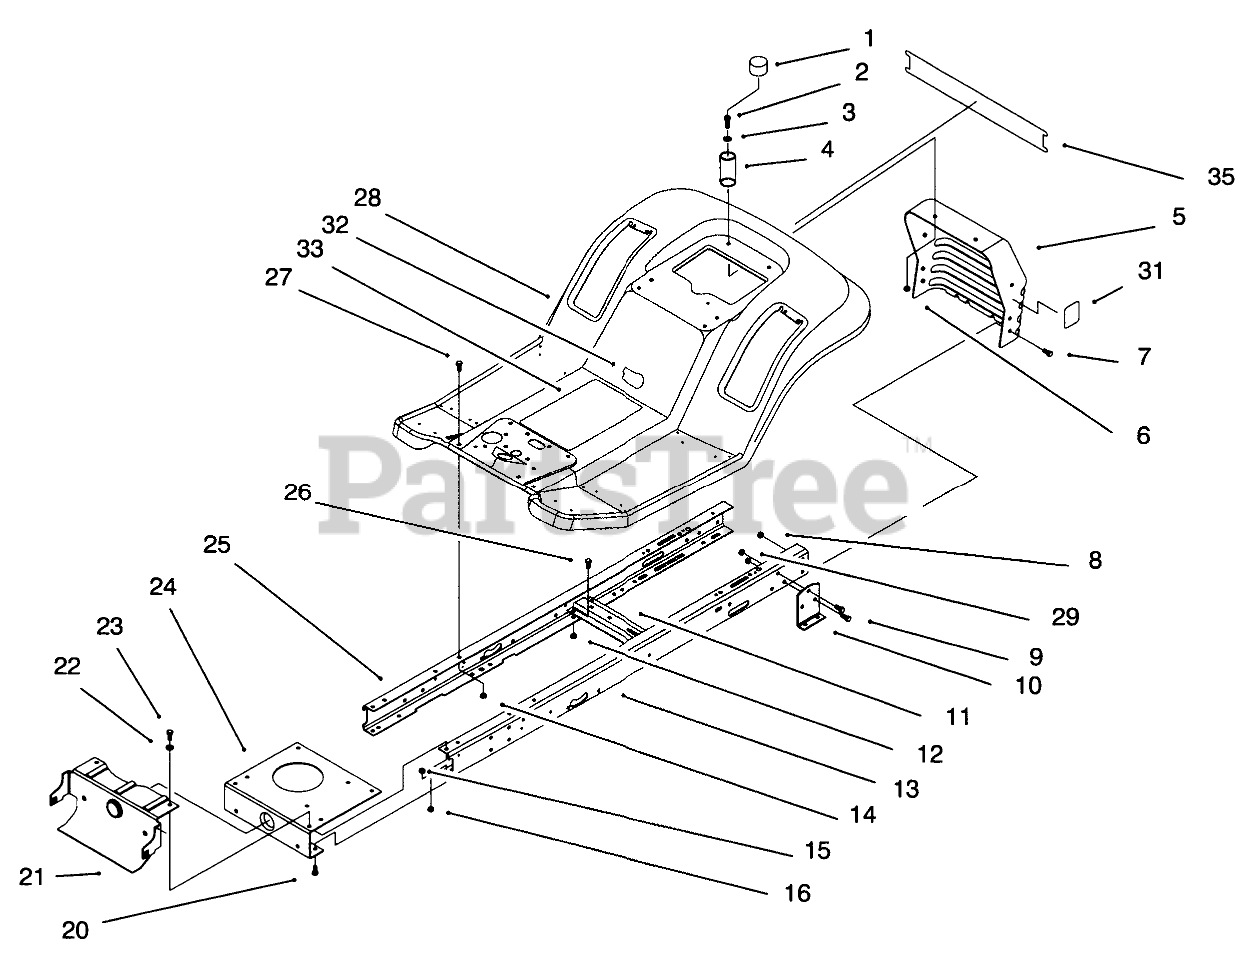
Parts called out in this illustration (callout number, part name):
1	CAP-PROTECTOR
2	SCREW-HH
3	WASHER-PLAIN
4	SPRING-COMPRESSION
5	Panel-Rear
6	NUT-LOCK, NI
7	SCREW-HH
8	NUT-LOCK, NI
9	SCREW-HH
10	BRACKET-TRANSAXLE, MOUNTING
11	BRACKET-IDLER PIVOT
12	NUT-LOCK, NI
13	Frame Rail-LH
14	NUT-LOCK, NI
15	NUT-LOCK, NI
16	NUT-LOCK, NI
20	SCREW-HH
21	Support-Front Axle
22	WASHER-PLAIN
23	SCREW-HH
24	PLATE-MOUNTING, ENGINE
25	Frame Rail-RH
26	SCREW-HH
27	SCREW-HH
28	BODY-REAR
29	NUT-LOCK, NI
31	DECAL - DUMP VALVE
32	Decal-USA (Only On: 71193)
33	Decal-Instruction (Only On: 71217)
33	Decal-Instruction (Only On: 71193)
35	DECAL-REAR BODY 1438 HXL
